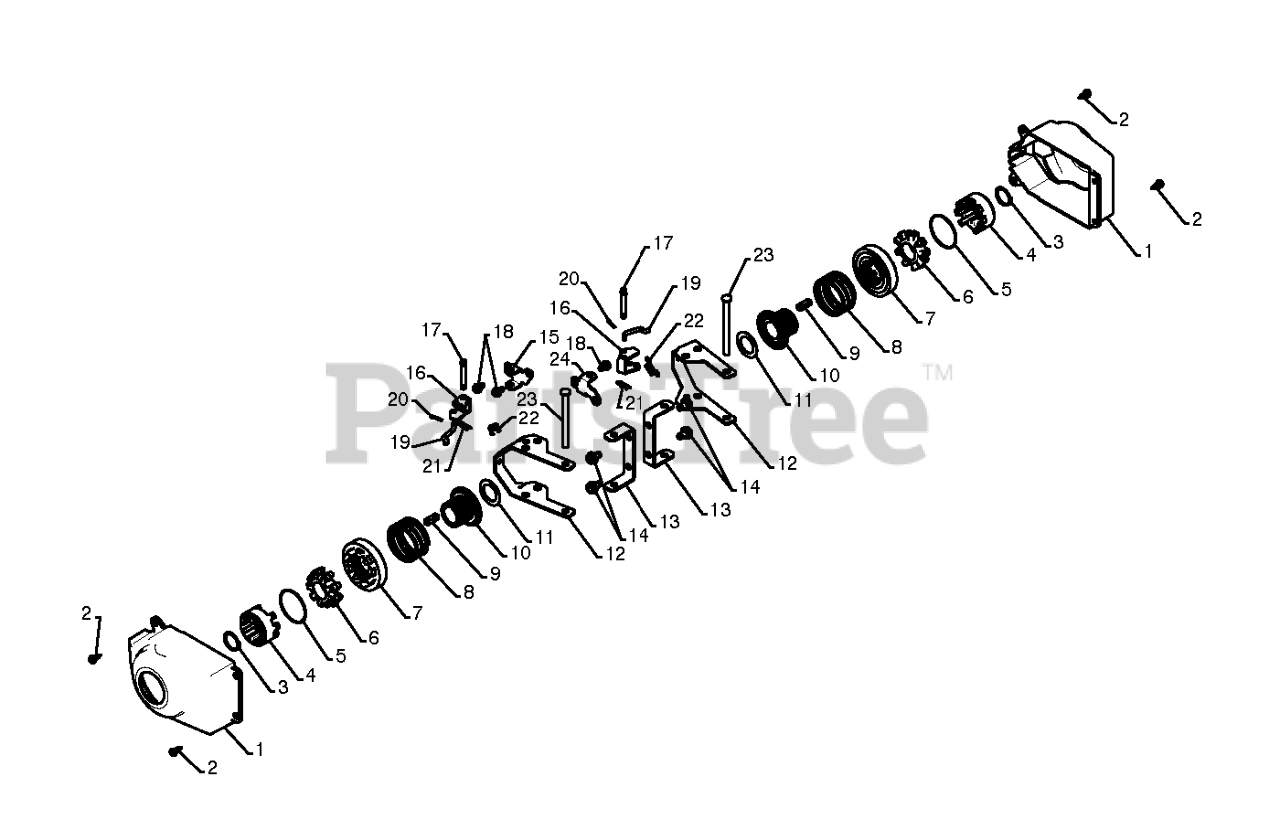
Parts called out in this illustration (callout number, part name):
1	COVER, POWER STEERING
2	SCREW, HEX HEAD, TAPPING
4	RP.DRIVER WHEEL
5	RING, WIRE RETAINER
6	LOBE WHEEL
7	RP.SLIDE.CLUTCH
8	SPRING, CLUTCH SLIDE
9	KEY, SQUARE 1/4 X .875
10	RP.LOBE.AXLE
11	WASHER TRUST 1"
12	YOKE, STEERING
13	BRACKET.STEER.PNT.BLACK
14	Screw 5/16-18 x 1/2 Hex, Self Tapping 5/16-18 x 1/2
15	BRKT.STEER.PIVOT.RH
16	BELLCRANK.STEER
17	PIN, STEERING BELLCRANK
18	SCREW 1/4X20
19	LINK.STEER.YOKE
20	RETAINER CLIP
21	RETAINER CLIP PM
22	SPRING LATCH
23	PIN, STEERING LEVER
24	BRACKET.STEER.PIVOT.LH.YZ
